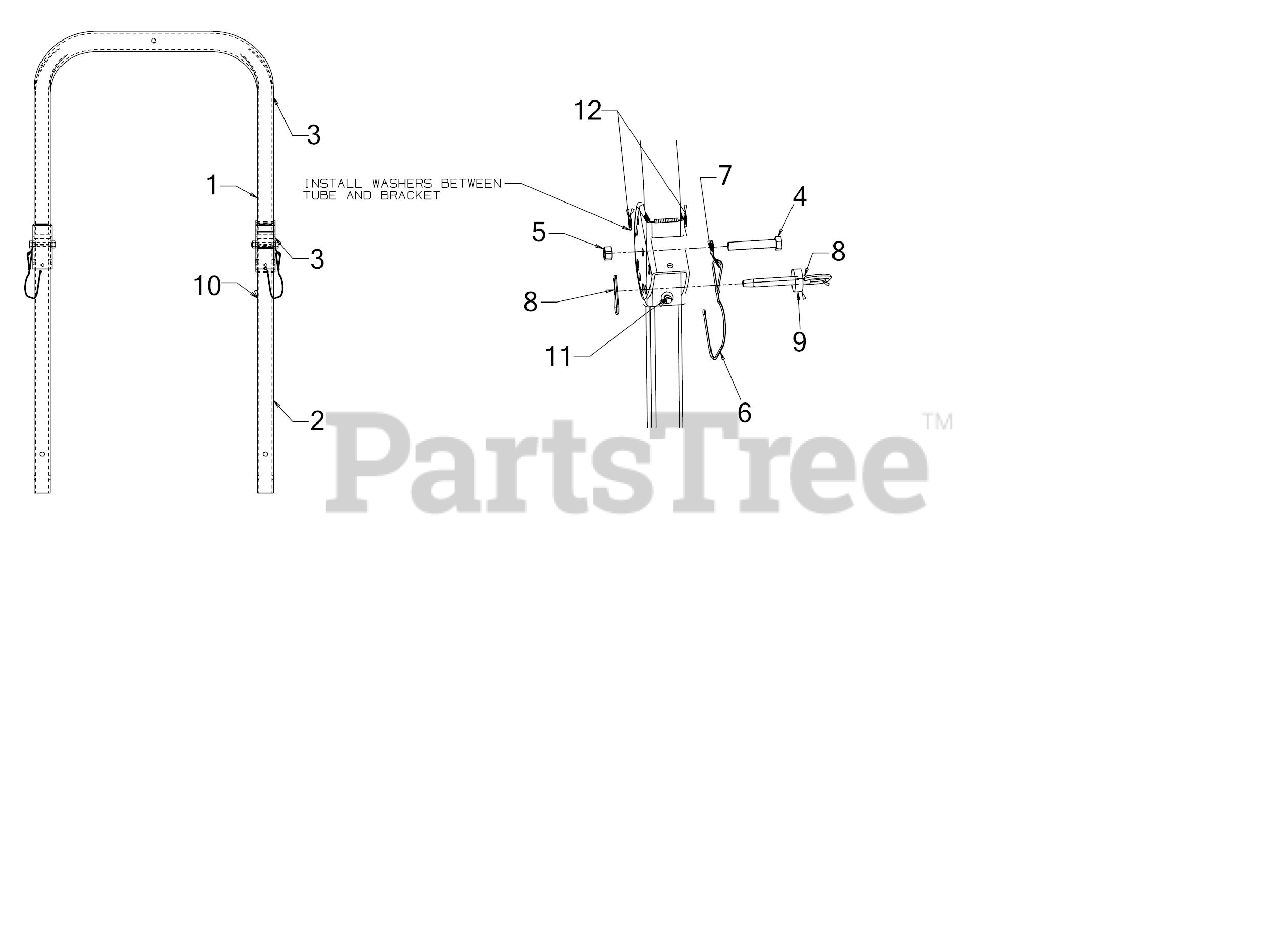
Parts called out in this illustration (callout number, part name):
1	DECAL, SERIAL
2	ROP TUBES R/L
3	UPPER ROPS
4	SCREW-HEX HEAD 3.00"
6	U-LOCK-NYLON
8	HITCH PIN
10	DECAL, ROPS WARNING
11	BUMPER-W/FLANGE
